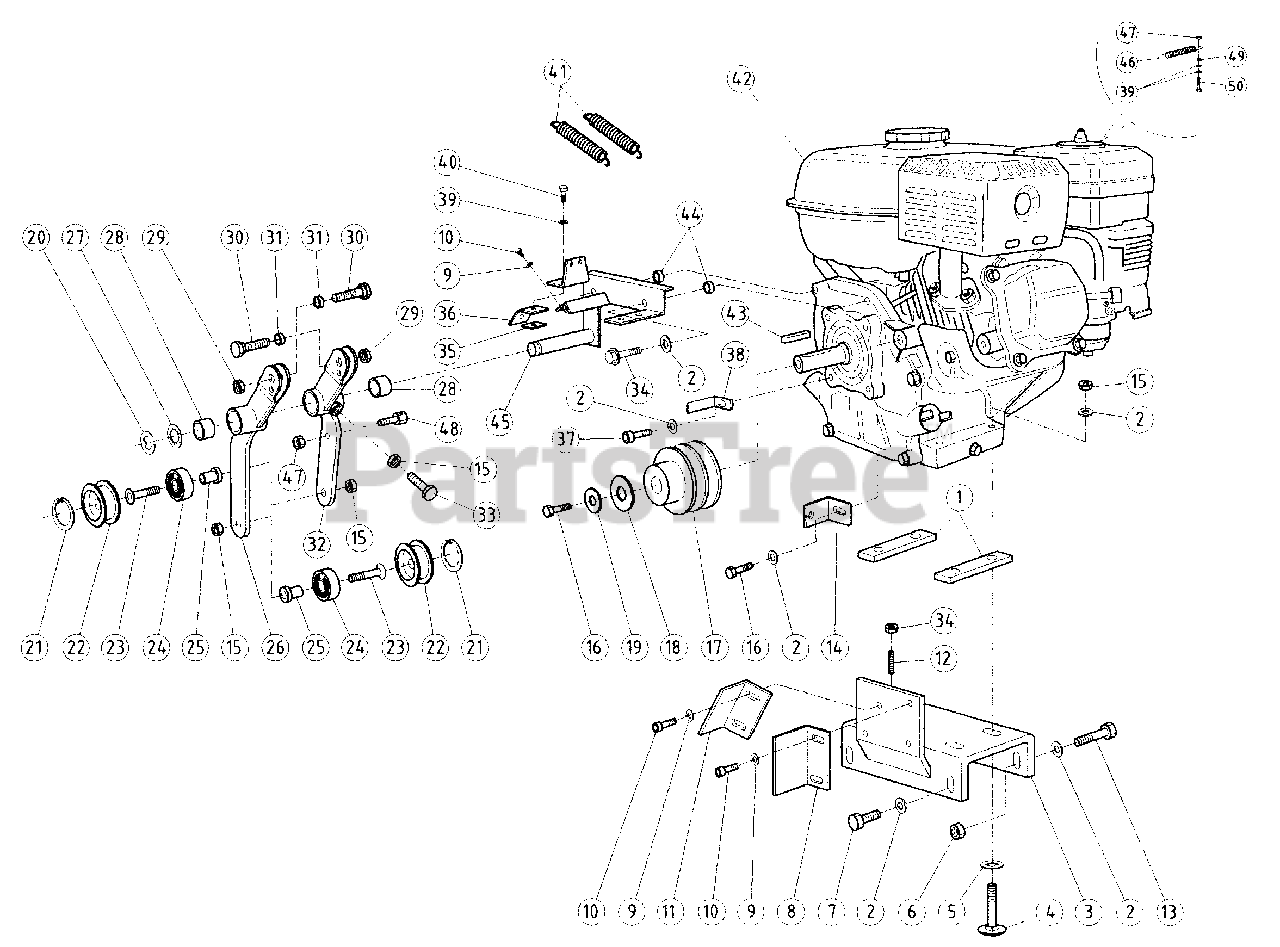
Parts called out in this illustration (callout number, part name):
1	Shim Engine 20x6
2	Washer Flat M8
3	Support Engine
4	Screw TTQST 8x40
5	Washer Toroidal M24
6	Nut Lock M8
7	Screwcap M8x16
8	Guide Belt No. 1
9	Washer Flat M5
10	Screw Allen M5x8
11	Guide Belt
12	Dowel M8x35
13	Screwcap M8x20
14	Bracket Guard Support
15	Nut M8 H5
16	Screw 5/16 x 3/4 mm 19
17	Pulley Engine Sect. H
18	Washer Flat M8x32
19	Washer Wave M8
20	Ring Radial elastic D 10
21	Ring Snap Internal 132
22	Roll Tightening
23	Screwcap M8x25
24	Bearing 12x32x10 6201 2RS
25	Bushing Bearing
26	Tensioner Belt
27	Shim adjustment 12.2x24x0.8
28	Bushing Self-lubricating
31	Clamp spacer
32	Tensioner Belt Threaded
33	Screw Tensioner
34	Screwcap M8 X 40
35	Nut Special
36	Bracket Guard Fixing
37	Screwcap 5/16-24 x 5/8
38	Bracket Front 15x3
39	Washer Flat M6
40	Screwcap M6 x 14
41	Spring Cable Return
42	Engine Honda 5.5 GX160K1QX2
43	Key 4.8x4.8x32
45	Support Tightener
46	Spring Accelerator Return
47	Nut Lock M6 H6
48	Drum Wire Holder
49	Nut M6 H4
50	Screwcap M6 X 18
